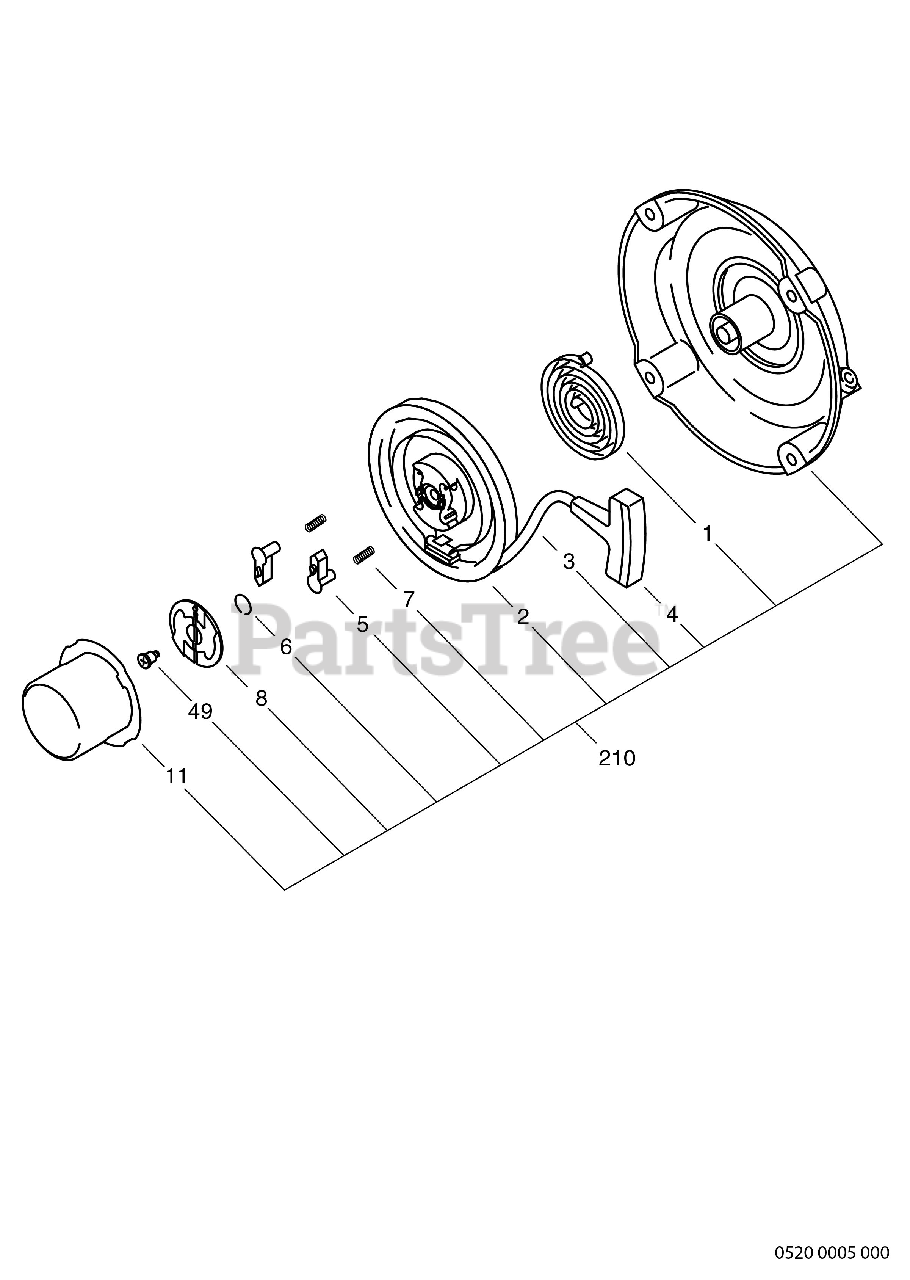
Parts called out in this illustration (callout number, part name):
1	SPIRAL SPRING
2	REEL
3	STARTER ROPE
5	RATCHET
6	FRICTION SPRING
7	RETURN SPRING
8	RACHET GUIDE
11	STARTER PULLEY
210	RECOIL STARTER AY
